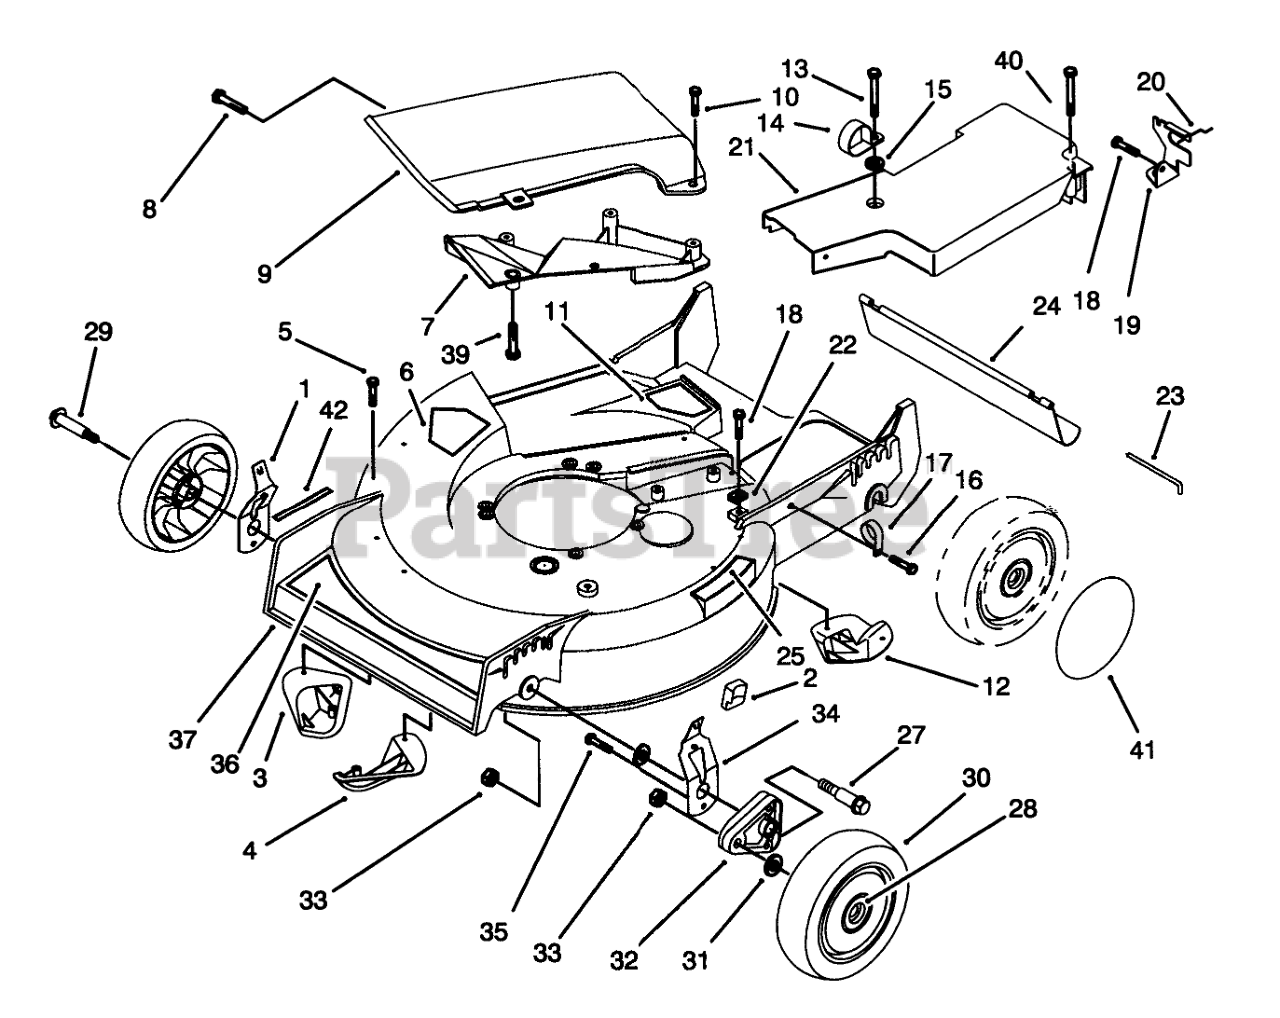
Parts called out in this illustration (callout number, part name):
1	RH SPRING ARM ASM
2	KNOB-ARM
3	KICKER-FRONT
4	KICKER-RH
5	SCREW-PPH
6	DECAL-DANGER
7	Deflector-Recycler
8	SCREW AND WASHER ASM
9	Recycler Cover Assembly (Incl. Ref. #7 & 39)
10	SCREW-HWH
11	DECAL - DANGER
12	KICKER-REAR
13	SCREW-SPECIAL
14	CLAMP-CABLE
15	WASHER
16	SCREW-HWH
17	CLAMP-CABLE
18	SCREW-HWHTF
19	Bracket-Adj. Trac
20	RETAINER-CABLE
21	BELT COVER
22	CLAMP-CABLE
23	ROD-SHIELD
24	SHIELD-TRAILING
25	DECAL - STEP PAD INT'L
27	BOLT-SHOULDER
28	BUSHING
29	BOLT-WHEEL
30	Wheel & Tire Assembly (Incl Ref. #28)
31	WASHER
32	ARM-PIVOT, FRONT
33	NUT-LOCK
34	LH SPRING ARM ASM
35	SCREW-HWH
36	DECAL - DECK
37	Housing Assembly (Incl. Ref. #3-6,8,11,12,&42,Pg.1)(Incl. Ref. #5-6,Pg. 3)(Incl. Ref. #30-30, Pg.4)
39	Screw-Plastite
40	SCREW-HHFTF
41	WHEEL COVER
42	DECAL - HOC
